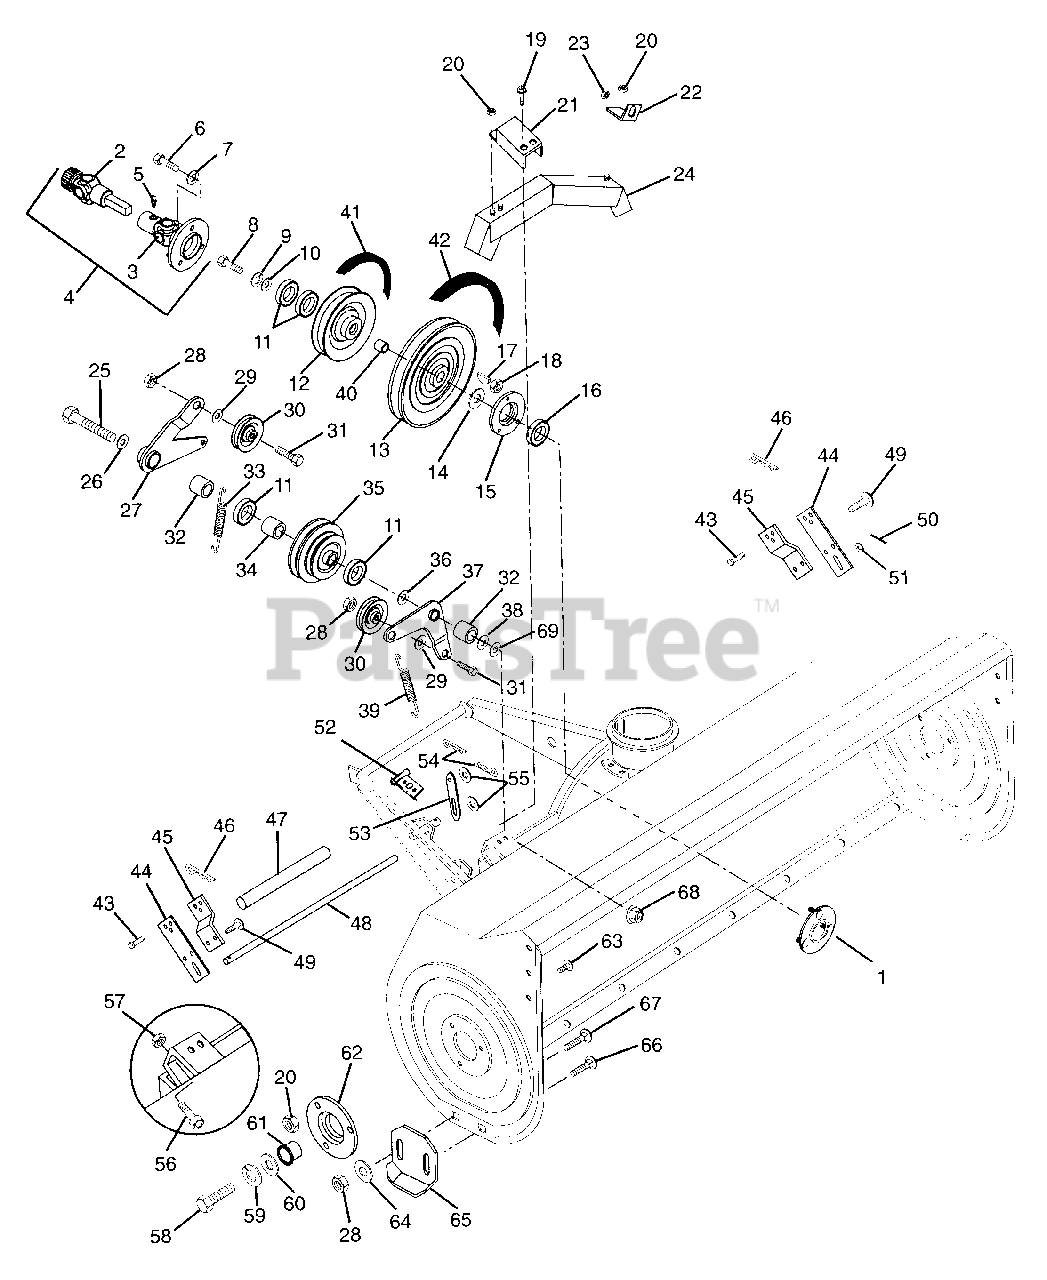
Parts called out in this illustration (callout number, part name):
1	BEARING FLANGE
2	UNIVERSAL SPLINE HALF W/ LOK
3	UNIVERSAL PLATE HALF
4	SHAFT, U-JOINT SNO HEAD
5	FTG-LUBE .25-28X.256 YWZC
6	@BLT-HEX .25-20X.75 GR5 YWZC
7	@WSHR-LK .25X.062 REG YWZC
8	@BLT-HEX .38-16X1.00 GR5 YWZC
9	@WSHR-LK .38X.094 REG YWZC
10	@WSHR-FL-STL.438X1.00X.083 YWZ
11	BRG-BALL .750X1.781X.61
13	PLY-V 10.00 X .88 W/KEY SALEM
14	WSHR-FL-STL .880X1.250X.062YWZ
15	BEARING FLANGE
16	BRG-BALL1.0X2.0X.56
17	KEY-WDRF .188X.875X.375 SAE11
18	@NUT-LK-CTR .25-20 YWZC
19	@SCR-TAP .25-20X.50 HWH TR YWZ
20	@NUT-SPNLK-FLG .25-20 YWZC
23	@NUT-LK-NYL .312-18 YWZC
24	BELT GUARD
25	@BLT-HEX .75-10X5.50 GR5 YWZC
26	WSHR-FL-STL.755X1.375X.062YWZC
27	IDLER ARM
28	@NUT-LK-CTR .38-16 YWZC
29	WSHR-FL-STL .406X.875X.135
30	IDLER-FLAT 3.00 X .38 CLK.&CAP
31	@BLT-HEX .38-16X1.25 GR5 YWZC
32	BSHG-SLV .750X1.125X1.062
33	SG-TENS .109X1.00X6.0
34	SPACER .781X1.000X.547
36	WSHR-FL-STL .781X1.500X.188
37	IDLER ARM
38	WSHR-HDND-THRST .755X1.40X.062
39	SG-TENS .109X1.00X6.0
40	SPACER .906X1.125X.453
41	V-BELT, HA-RAW EDGE
42	V-BELT, 4L-RAW EDGE
43	CLEVIS PIN
44	LIFT LINK
45	SUPPORT
46	PIN-HAIR INT .08X.18X1.18
47	TUBE .725 X .875 X 14.00
49	@SCR-TAP .31-18X.50 HWH TR YWZ
50	@PIN-CTR .12X1.25 EXTPRSQCT YZ
51	WSHR-FL-STL .688X1.75X.134PL
52	LIMITING POST
53	LIMITING ARM
54	PIN-HAIR-INT .09X.188X2.00YWZC
55	@WSHR-FL-STL.531X1.06X.095YWZC
56	SCR-SKH 10-24X.38
57	NUT-LK DUAL FACE 10-24 PL
58	@BLT-HEX .50-13X1.00 GR5 YWZC
59	WSHR-LK .500X.151 HVY YWZC
60	WSHR-FL-STL.511X1.441X.125 YWZ
61	BSHG-FLG 1.000X1.12X.62X1.50BR
62	BEARING SUPPORT
63	BLT-SERNK SL .25-20X.50 YWZC
64	@WSHR-FL-STL.38X.875X.083 YWZC
65	RUNNER - SKID SHOE
66	BLT-RHHDSQSHNK .38-16X.75 G2YZ
67	@BLT-RDHDSQNK .38-16X1.00 G2YZ
68	@NUT-LK-CTR .75-10 YWZC
69	WSHR-FL-STL.755X1.375X.062YWZC
